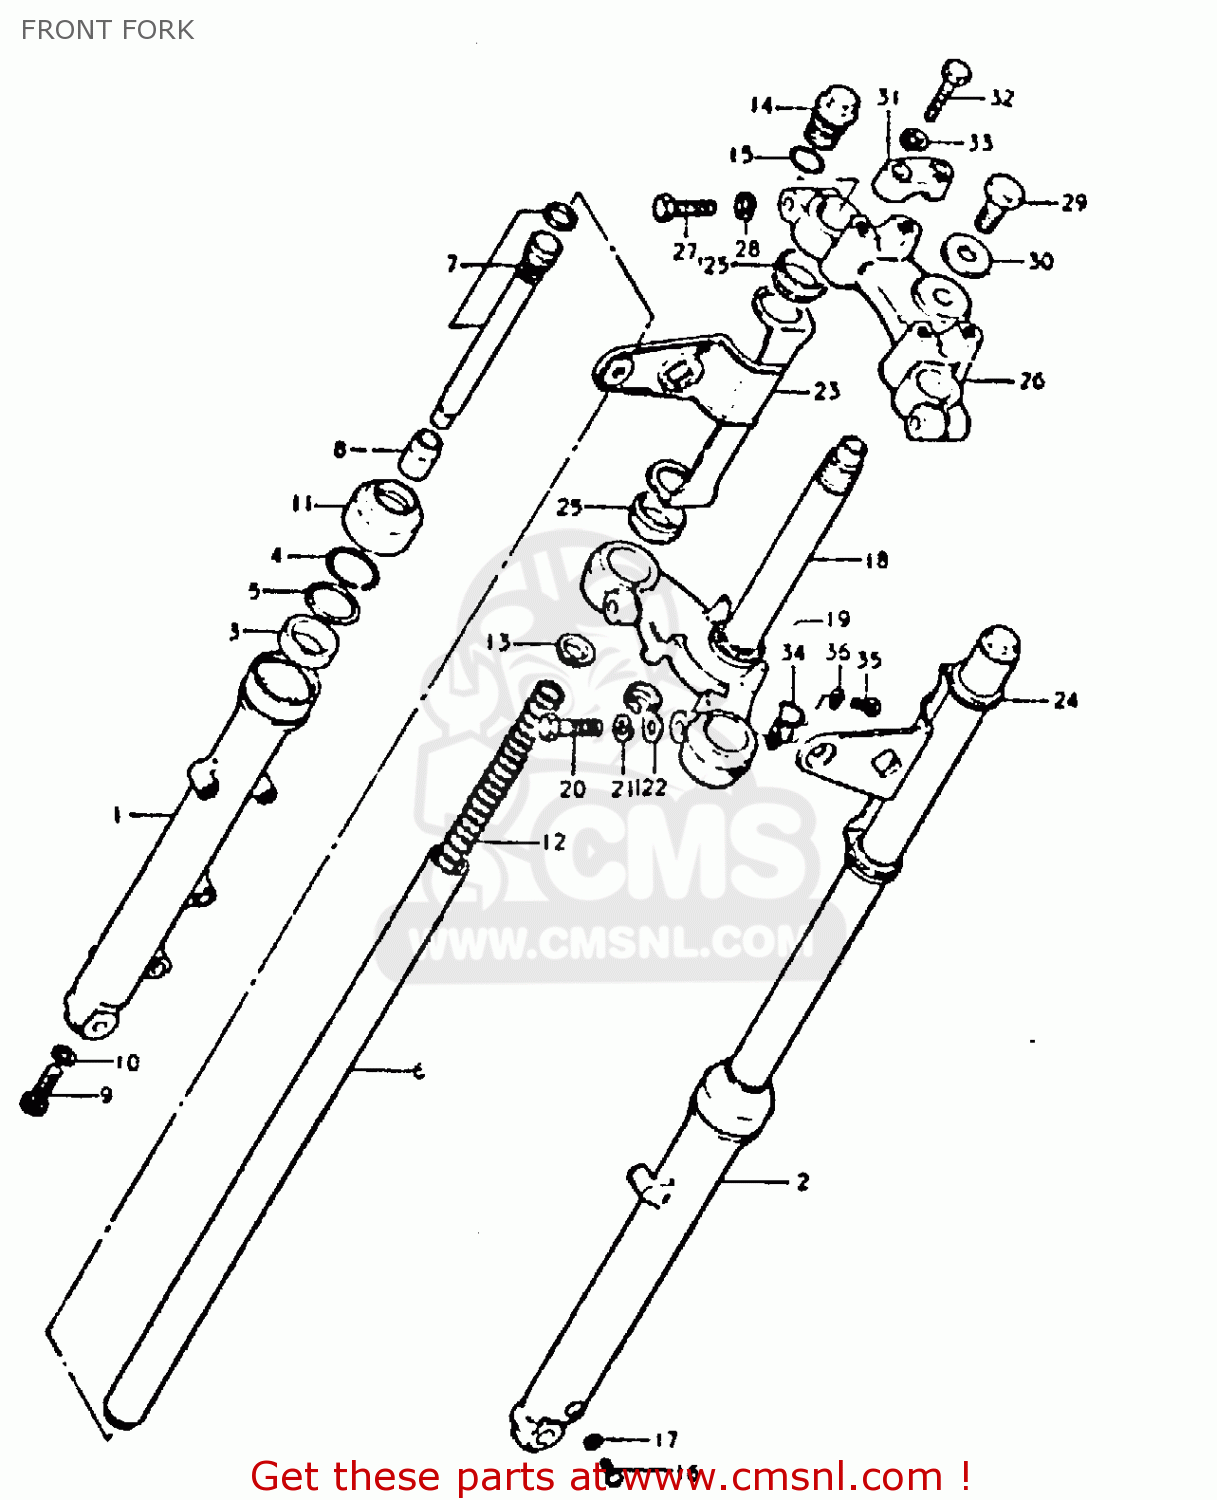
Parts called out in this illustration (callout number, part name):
1	OUTER TUBE, RH
2	OUTER TUBE, LH
3	OIL SEAL,FRONT FORK
4	RING,SNAP
5	WASHER
6	TUBE,INNER
7	CYLINDER
8	PIECE,OIL LOCK
9	BOLT,FORK CYLINDER(10X25)
10	GASKET (NAS)
11	SEAL,DUST
12	SPRING
13	GUIDE,SPRING COVER
14	CAP
15	O-RING,FORK INNER TUBE
16	SCREW
17	GASKET,DRAIN,PLUG (NAS)
18	STEM,STEERING
19	RACE,STEERING OUTER LWR
20	BOLT
21	WASHER,LOCK 12
22	CLIP
23	BRACKET, HEADLAMP RH
24	BRACKET, HEADLAMP LH
25	CUSHION,HEADLAMP BRACKET
26	HEAD,STEERING STEM(BLACK)
27	BOLT,FORK INNER TUBE F
28	LOCK WASHER
29	BOLT,FORK INNER TUBE
30	WASHER,STEM HEAD(10.5X30X3.2)
31	HOLDER,HANDLE(BLACK)
32	BOLT
33	LOCK WASHER
34	CLIP,BRAKE CABLE
35	SCREW
36	LOCK WASHER
